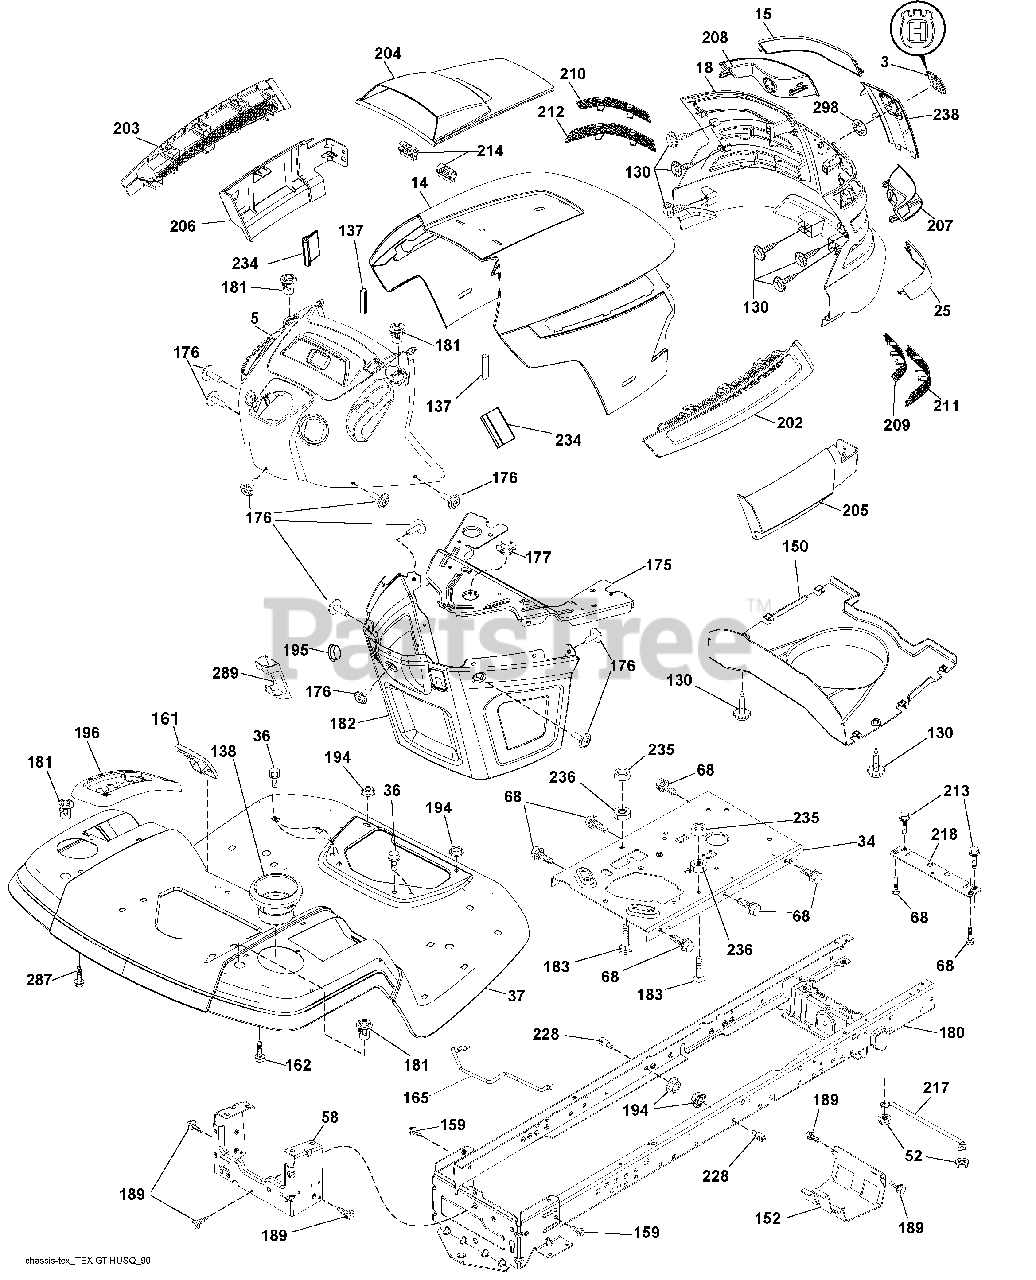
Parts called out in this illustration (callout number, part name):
3	Logo
14	Hood
34	Plate Engine
36	Screw 5/16-18 X 3/4
52	Nut Crown Lock 5/16
58	Drawbar Upper
68	Screw Thdrol 5/16-18 X 1/2
130	Screw #10 X 0.750 Bos Thread
137	Bumper Dash
138	Cupholder
152	Shield Browning
159	Screw Hexwash Thor 3/8-16 X 3/4
161	Window Fuel
165	Support Tank Rear
175	Crossmember Plate
176	Screw 10-24 X 5/8
177	Bushing Steering
181	Bushing Mtg. Fender Crgo
182	Dash Lower
183	Bolt 5/16-18 X 1-1/4 Full Thd
189	Screw 5/16-18 X 3/4
194	Nut Lock Hex Flange 5/16-18
196	Console Asm. Deck Lift
202	Vent Side Hood Rh
203	Vent Side Hood Lh
204	Vent Top Hood
205	Skirt Side Rh
206	Skirt Side Lh
209	Insert Hex Top Rh
210	Insert Hex Top Lh
211	Insert Hex Bottom Rh
212	Insert Hex Bottom Lh
213	Bolt 5/16-18 X 3/4
214	Clip Retainer
217	Rod Pivot Hood
218	X-Piece Hood Stop
228	Stud Fastener
234	Bumper Hood
235	Spacer Fender
236	Nut Lock 5/16-18 Unc
287	Screw Hex Washead 1/4-20 X 3/8
289	Plug Cruise/Phone
